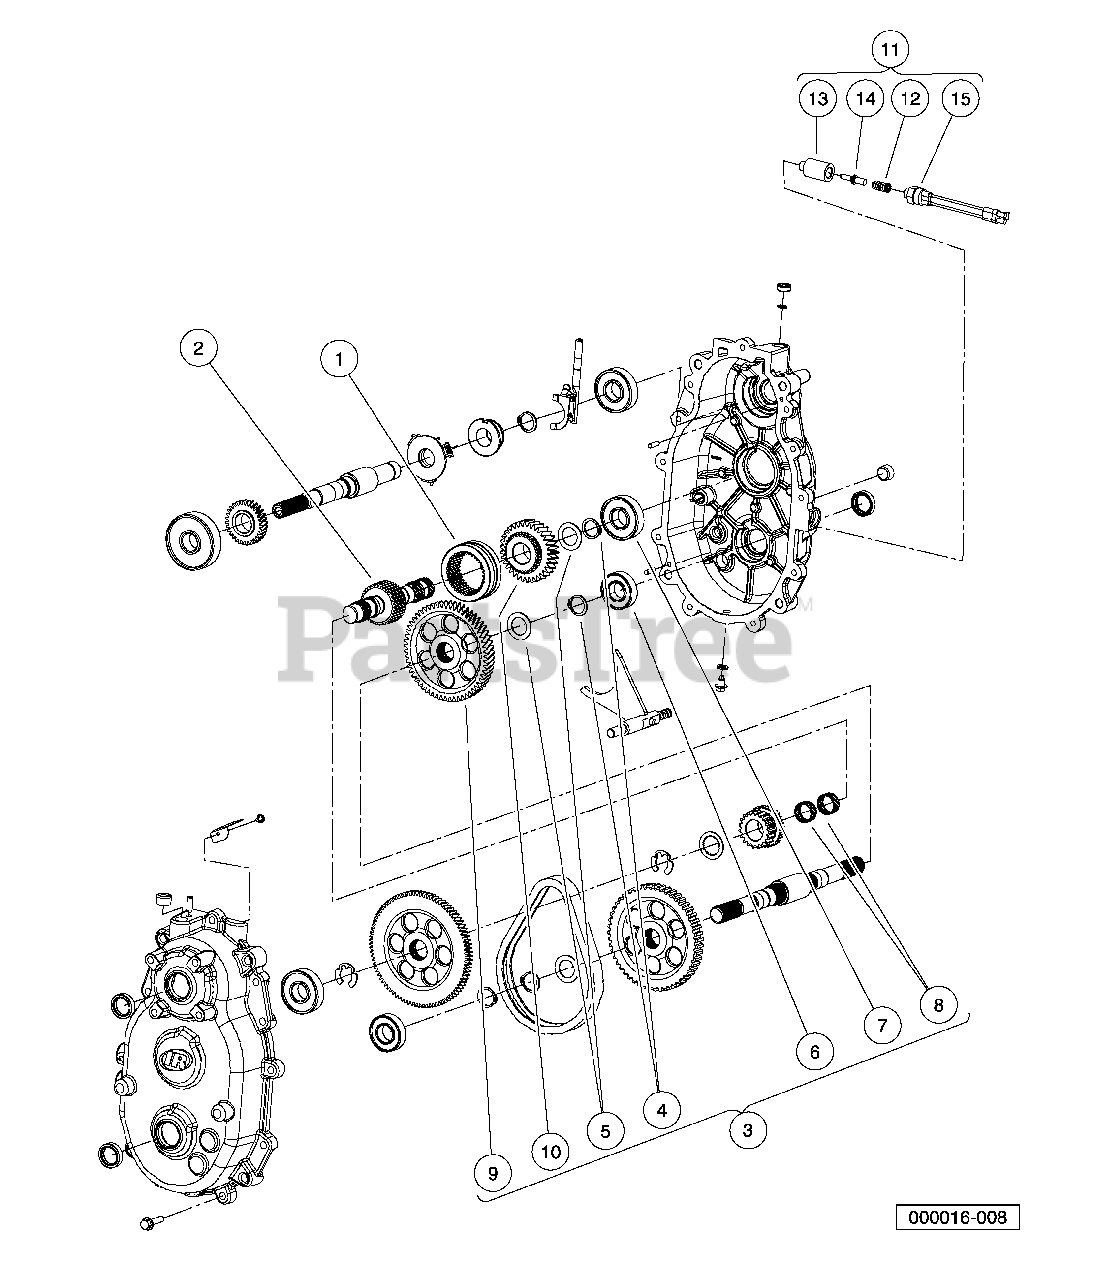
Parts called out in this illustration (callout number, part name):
1	Dog, Engagement
2	Shaft, Intermediate.
3	Kit, Forward Gear Repair
4	Ring, Retaining, Basic External
5	Washer, Thrust, 1.007 X .062
6	Bearing, Ball
7	Bearing, Ball
8	Bearing, Needle.
11	Kit, Neutral Switch Repair
13	Guide, Detent Bullet
14	Bullet, Detent
15	Switch, Indicator, Pollak
